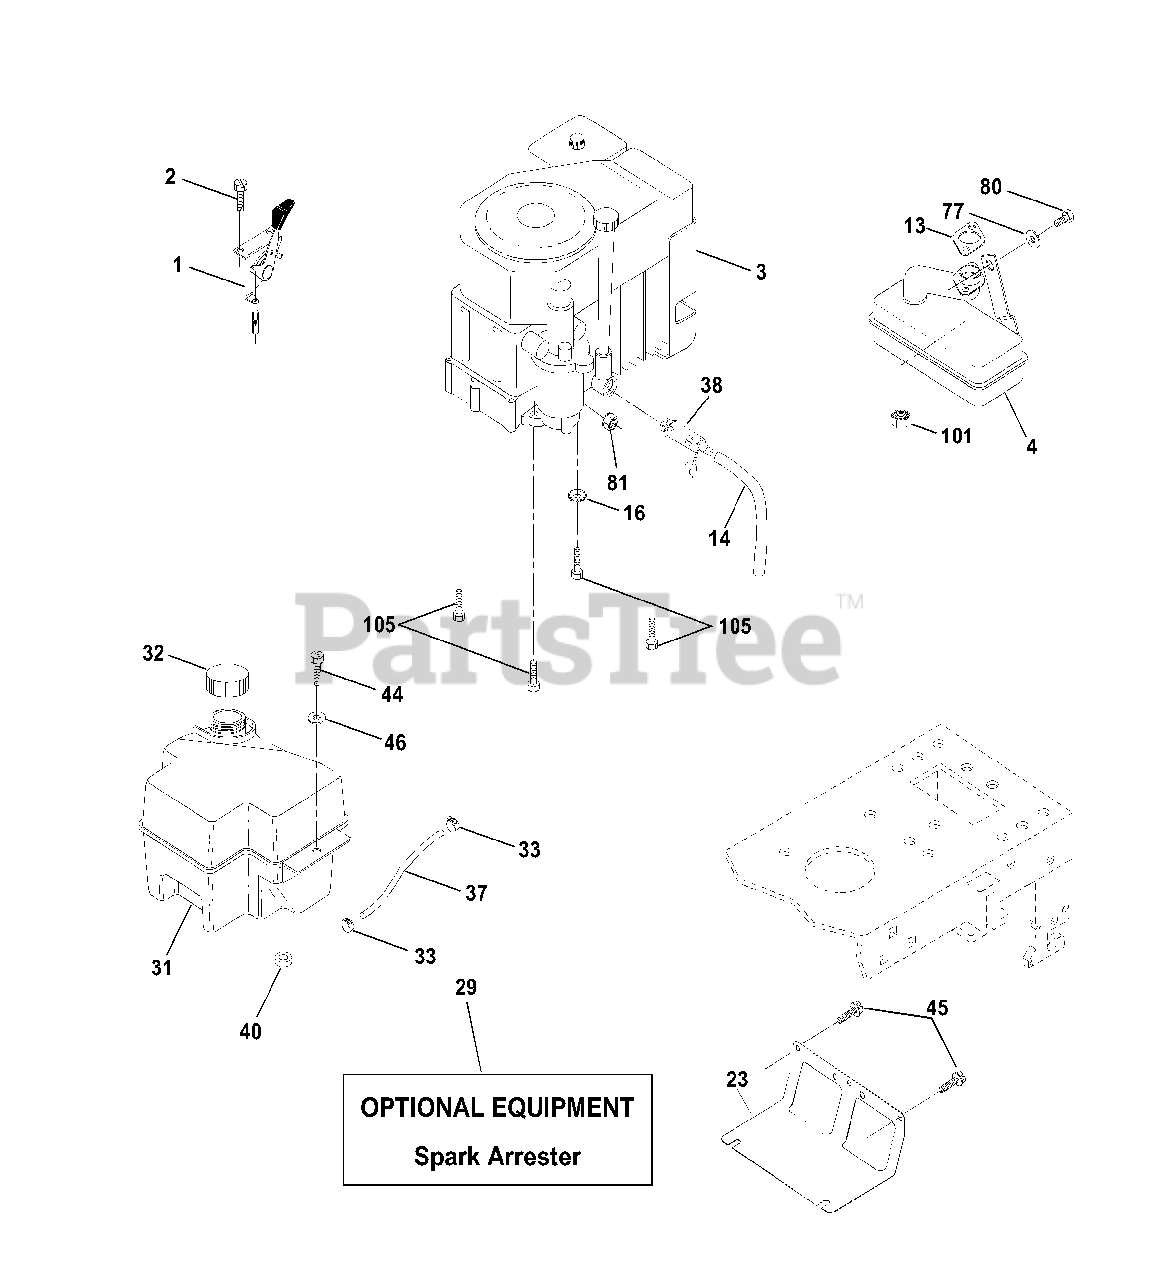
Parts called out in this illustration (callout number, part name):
1	Control Th/ch Flag
2	Screw Hex Thd Cut 1/4-20x5/8 T
4	Muffler
14	Tube Drain Oil Easy
16	Washer Lock Ext Tooth 3/8
23	Shield Brn/Dbr Guard
29	Kit Spark Arrestor (Flat Scrn)
31	Tank Fuel Front
32	Cap Asm Fuel W/sym Vented
33	Clamp Hose Black
37	Line Fuel 20"
38	Plug Drain Oil Easy
40	Bushing Snap Nyl Blk Fuel Line
44	Screw Hexwsh Thdrol 1/4-20x3/4
45	Screw Hexwsh Thdr 3/8-16 x 3/4
46	Washer 9/32 X 7/8 X 16 Ga
77	Washer 5/16 x 3/4 x 16 Ga.
80	Bolt Hex Hd 5/16-18 Unc x 1/2
81	Nut Keps Hex 1/4-20 UNC
101	Nut Flange M8-1.25
105	Screw 3/8-16 x 1
